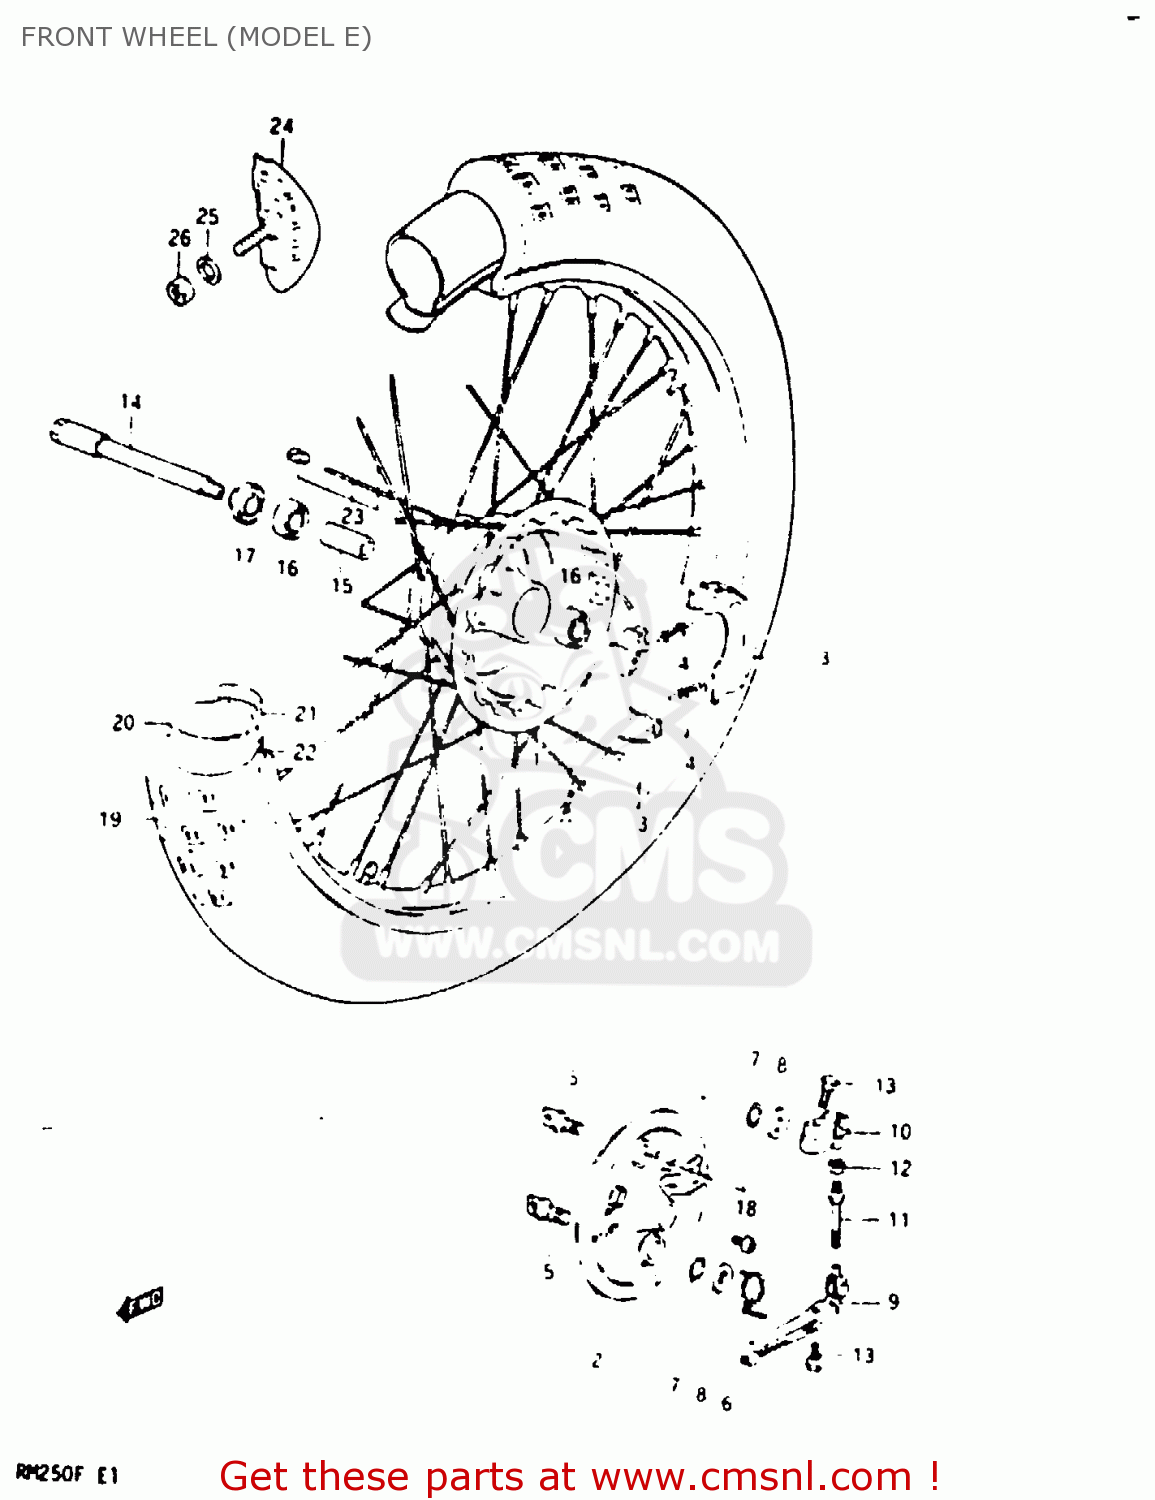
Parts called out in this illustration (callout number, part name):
1	DRUM,FRONT HUB
2	PANEL,FRONT HUB
3	SHOE,BRAKE (MCA)
4	SPRING
5	CAM,FRONT BRAKE
6	SPRING
7	O-RING (D:2 ID13.8)
8	WASHER (14.2X22X1)
9	SHOE SET,BRAKE
10	LEVER ASSY, BRAKE CAM, NO.2
11	ROD,BRAKE CAM LEVER CONNECTION
12	NUT 6MM
13	BOLT
14	AXLE,FRONT
15	SPACER,FRONT HUB BEARING
16	BALL BEARING 15X35X11
17	SPACER,FRONT AXLE,RIGHT
18	SCREW
19	TIRE,FRONT
20	TUBE
21	PROTECTOR,WHEEL,INNER
22	RIM,FRONT WHEEL (1.60X21)
23	SPOKE SET,FRONT
24	STOPPER,BEAD
25	WASHER
26	NUT 8MM
